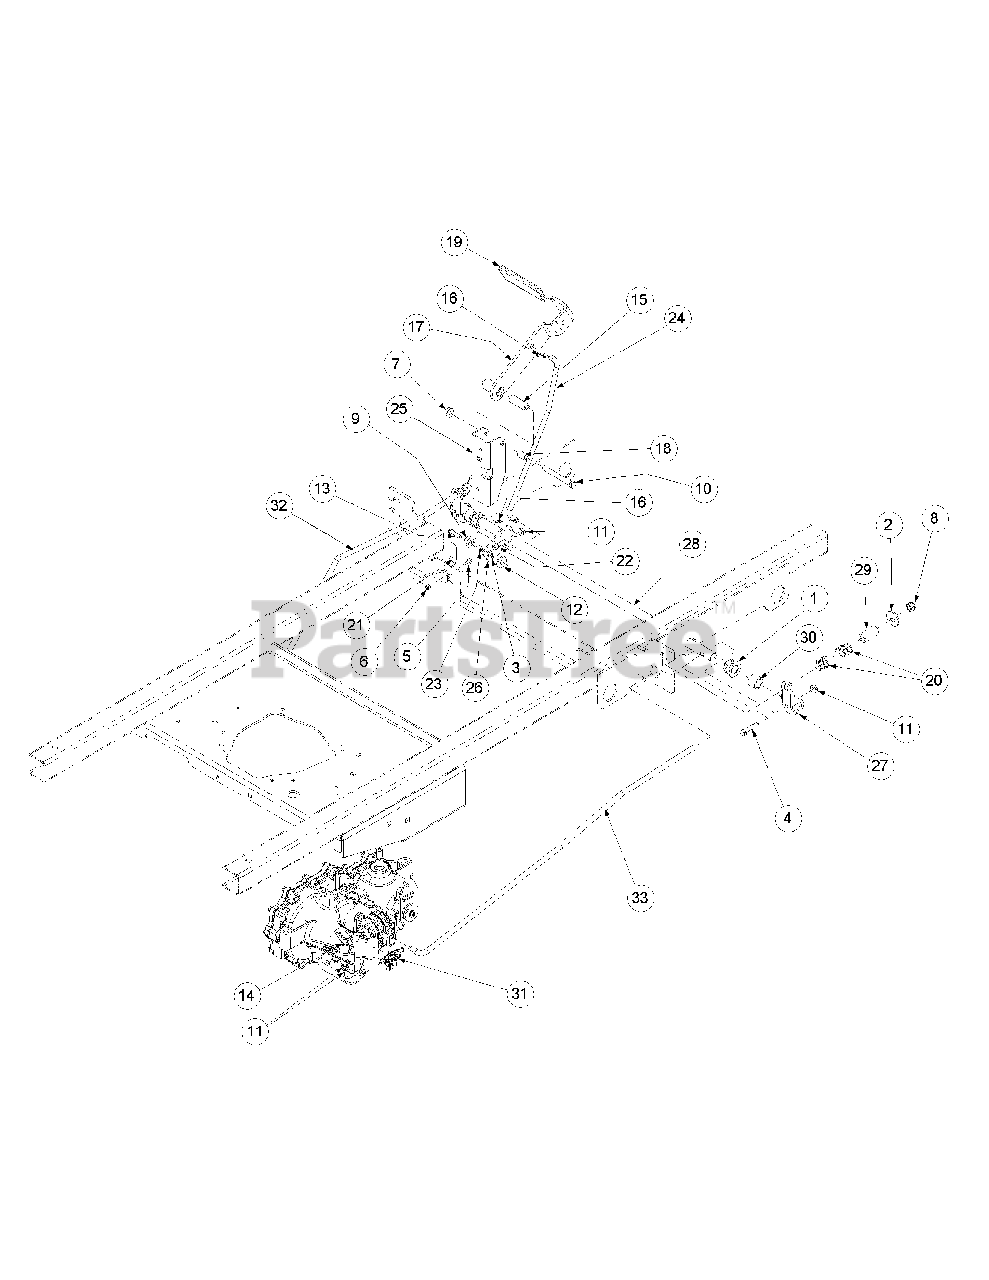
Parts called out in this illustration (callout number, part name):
1	Hex Flange Bearing, .752 ID
2	Washer, 1/2
3	Lock Nut, Nylon Insert, 1/4-20
4	Hex Cap Screw, 5/16-18 x 1-1/2
5	Screw, Hex Washer, 10-32 x 1/2
6	Lock Nut, Nylon Insert, 10-32
7	Nut, Flange Lock, 3/8-16
8	Nut, 7/16-14, Nylock
9	Spacer, Control Rod
10	Hex Cap Screw, 3/8-16 x 3-1/4
11	Nut, Lock, HexFlange, 5/16-18
12	Flat Washer, .406 ID x 1.0 OD x .105
13	Screw, TT, 1/4-20, 1.0, Hex Index Washer
14	Hex Cap Screw, 5/16-18 x 2.75
15	Spacer, .39 ID x .63 OD x 1.75
16	Hair Pin, INT .072 x 1.12 Lg.
17	Weldment, Brake Handle
18	Spacer, .375 x .50 x .75 Lg
19	Grip, Park Brake
20	Lift Handle Spring
21	Spring Retainer
22	Socket Head Capscrew, 5/16-18 x 1.50
23	Spacer, Pump Release
24	Rod Brake, Connect To Handle
25	Park Brake Mounting Bracket
26	Brake Arm Assembly
27	Brake Arm Bracket
28	Pivot Brake Shaft
29	Hose, .5 ID x .78 OD, Low Pressure
30	Spacer, .76 ID x 1.0 OD x 3/4
31	Spring Extension, .740 OD x 2.656
32	Brake Rod, LH
33	Brake Rod, RH
